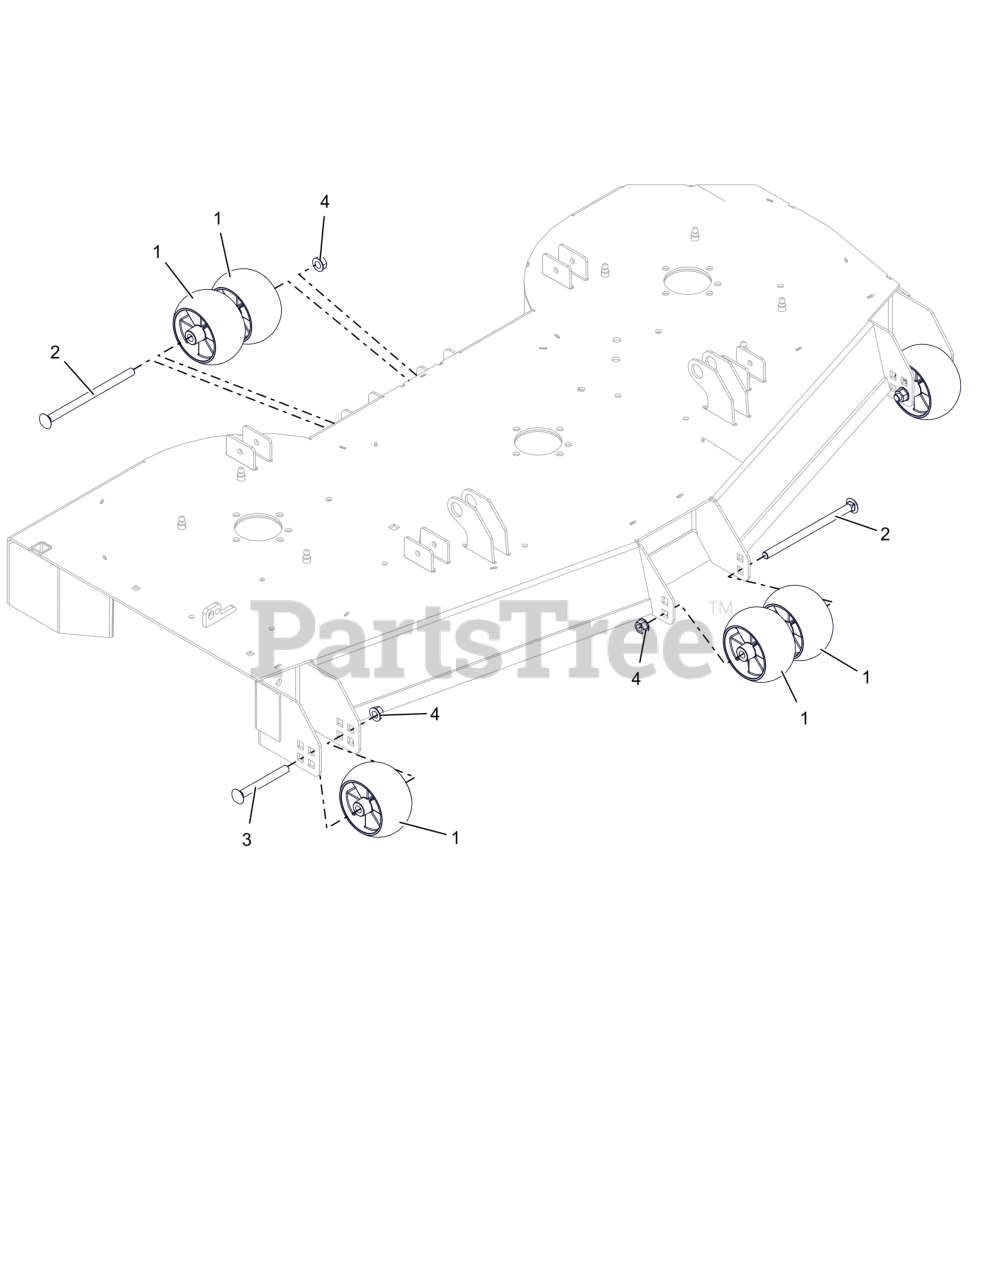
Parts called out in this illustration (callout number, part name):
1	WHEEL, ANTI SCALP - 5X3 CTR W/RIBS
2	BLT,RHSN .50-13X8.00 G5 ZCC NS
3	BLT,RHNS .50-13X4.50 G5 ZCC NS
4	NUT-LK-CTR-FLG .500-13 GG ZCC
